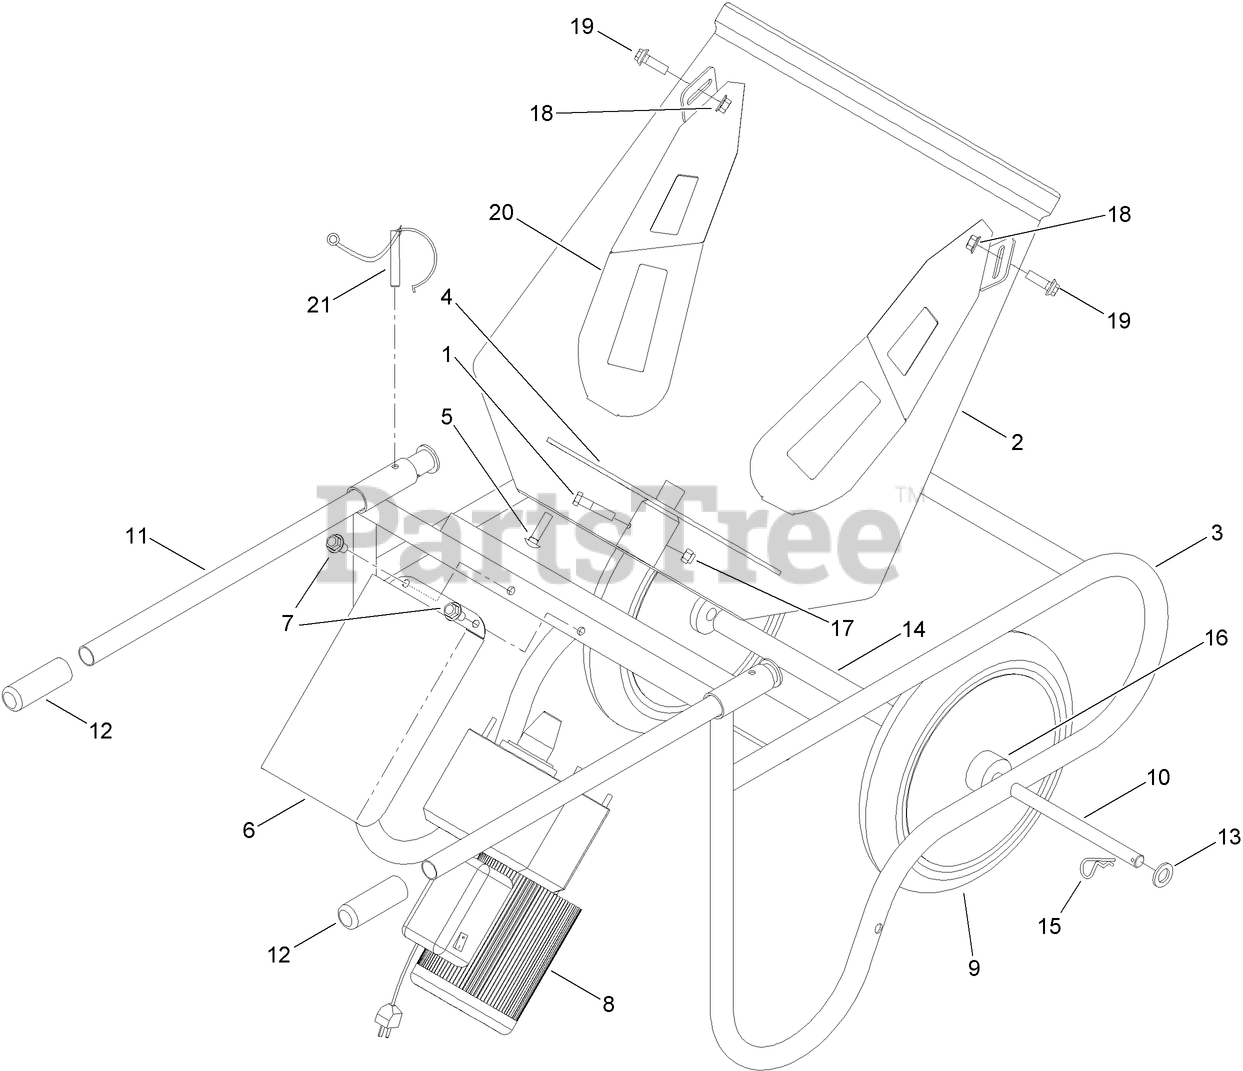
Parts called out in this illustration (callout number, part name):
2	DRUM-POLYETHYLENE
3	FRAME-WHEELBARROW
4	INSIDE PLATE ASM (W/ STRAIGHT BUSHING)
5	SCREW-HHF
6	COVER-MOTOR
7	SCREW-WHIZLOCK
8	GEAR MOTOR ASM
9	FLAT FREE WHEEL ASM
11	HANDLE-FRAME
12	GRIP-HANDLE
13	WASHER
14	SPACER-TUBE, AXLE
15	CLIP-R
16	BEARING-WHEEL
17	NUT-HHF, WHIZ
18	NUT-HF
19	SCREW-HHF
20	BLADE-MIXING
21	PIN-LOCKING (W/ LANYARDS)
